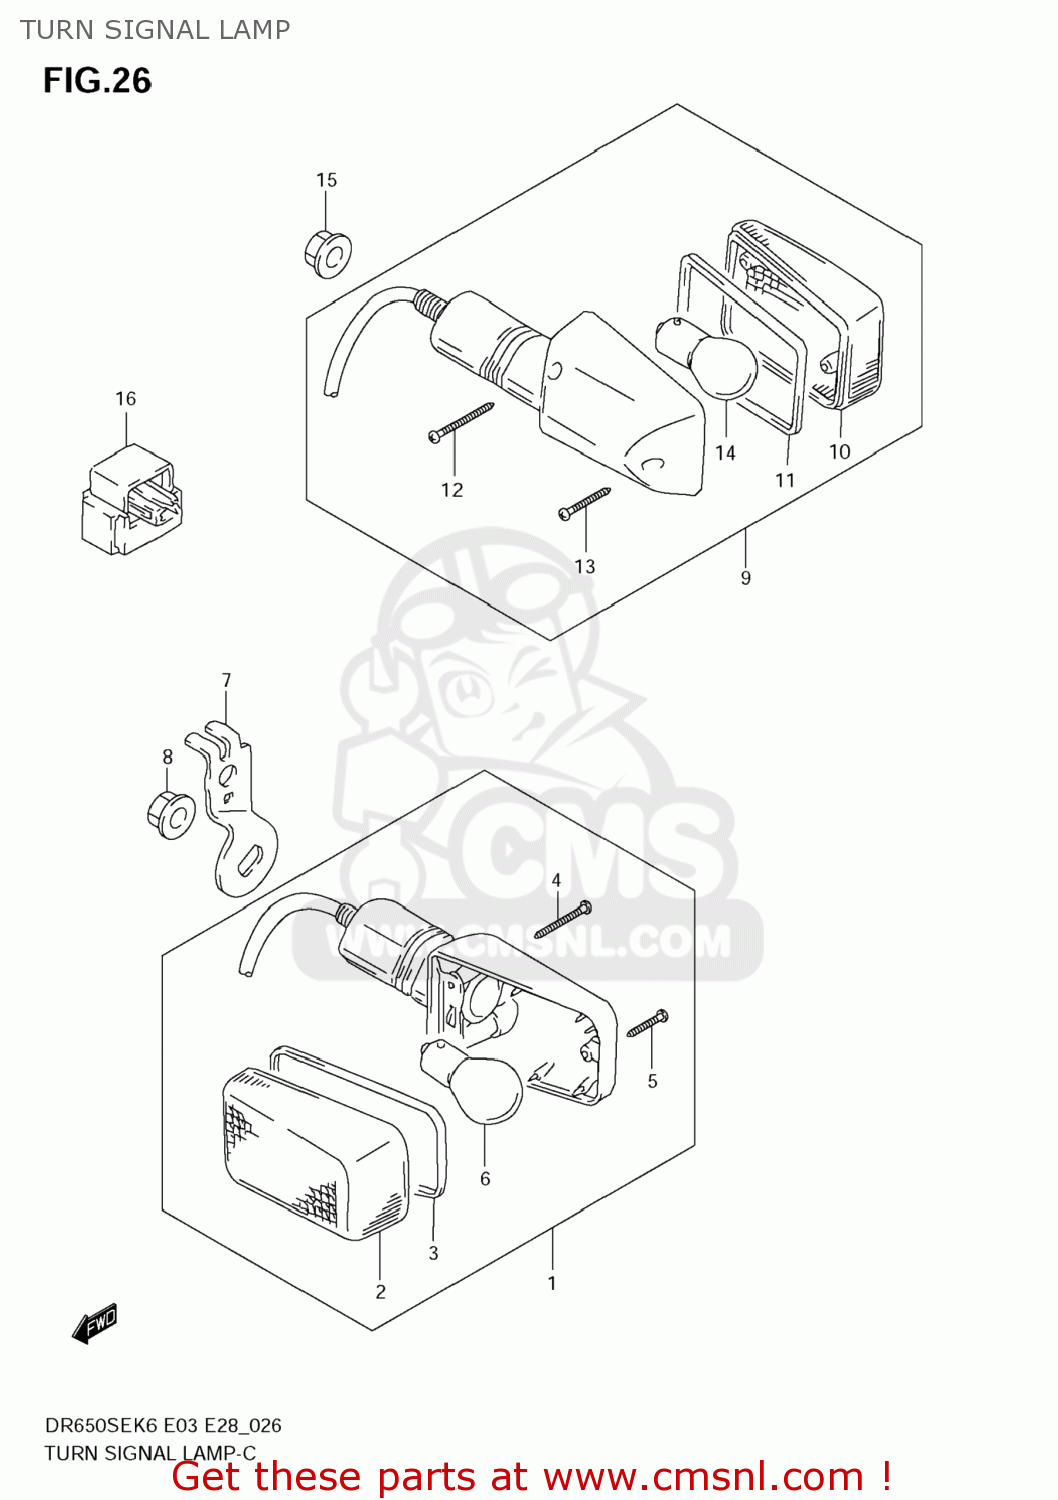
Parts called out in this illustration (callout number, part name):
1	LAMP ASSY,FR TURN SIGNAL
2	LENS
3	GASKET (NAS)
4	SCREW(3X30)
5	SCREW
6	BULB(12V21W)
7	BRACKET,FR TURNSIGNAL,R
8	NUT
9	LAMP ASSY,RR TURNSIGNAL,R
10	LENS
11	GASKET (NAS)
12	SCREW(3X30)
13	SCREW
14	BULB(12V21W)
15	NUT
16	RELAY ASSY
